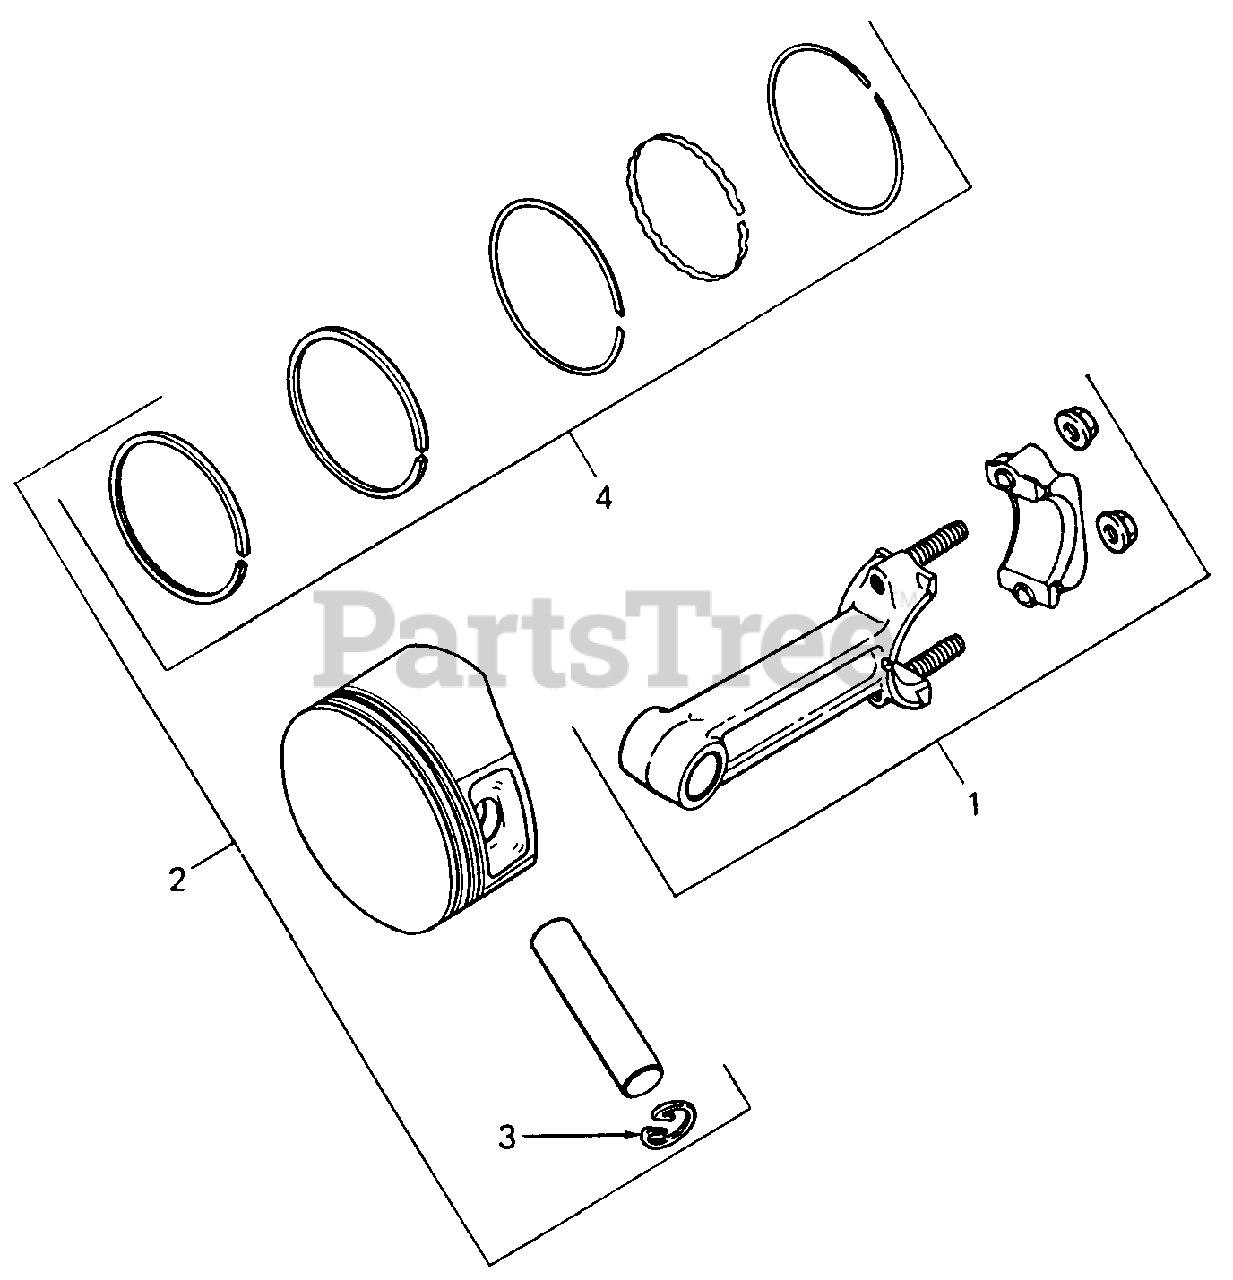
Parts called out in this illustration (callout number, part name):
1	Rod, Connecting (Std)
2	Piston w/Ring Set (Std)
3	Retainer, Piston Pin
4	Ring Set (Std & .003)
